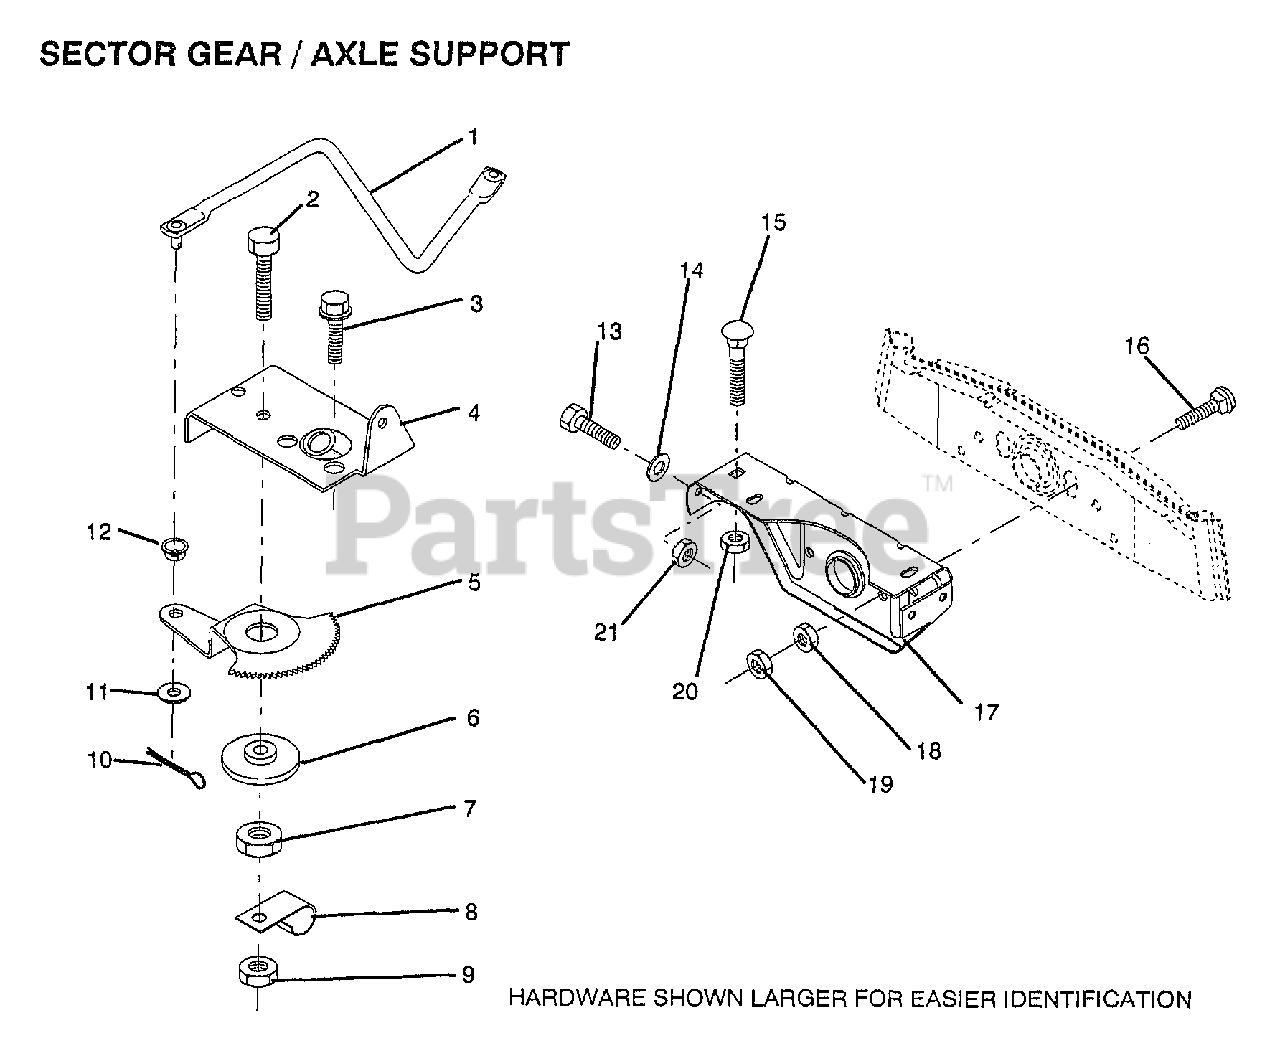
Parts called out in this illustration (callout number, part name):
2	"BOLT,HEX"
3	SCREW LT
4	"PLATE,STR SUPT"
5	GEAR SECTOR
6	BUSHING
7	NUT
8	CLIP INSULATOR
9	NUT LTV
10	COTTER PIN
11	WASHER
12	BUSHING.DRAGLINK
13	BOLT
14	WASHER
15	BOLT
16	BOLT
17	"SUPT,FRT AXLE"
18	NUT.HEX.3/8-16UNC
19	LOCKNUT
